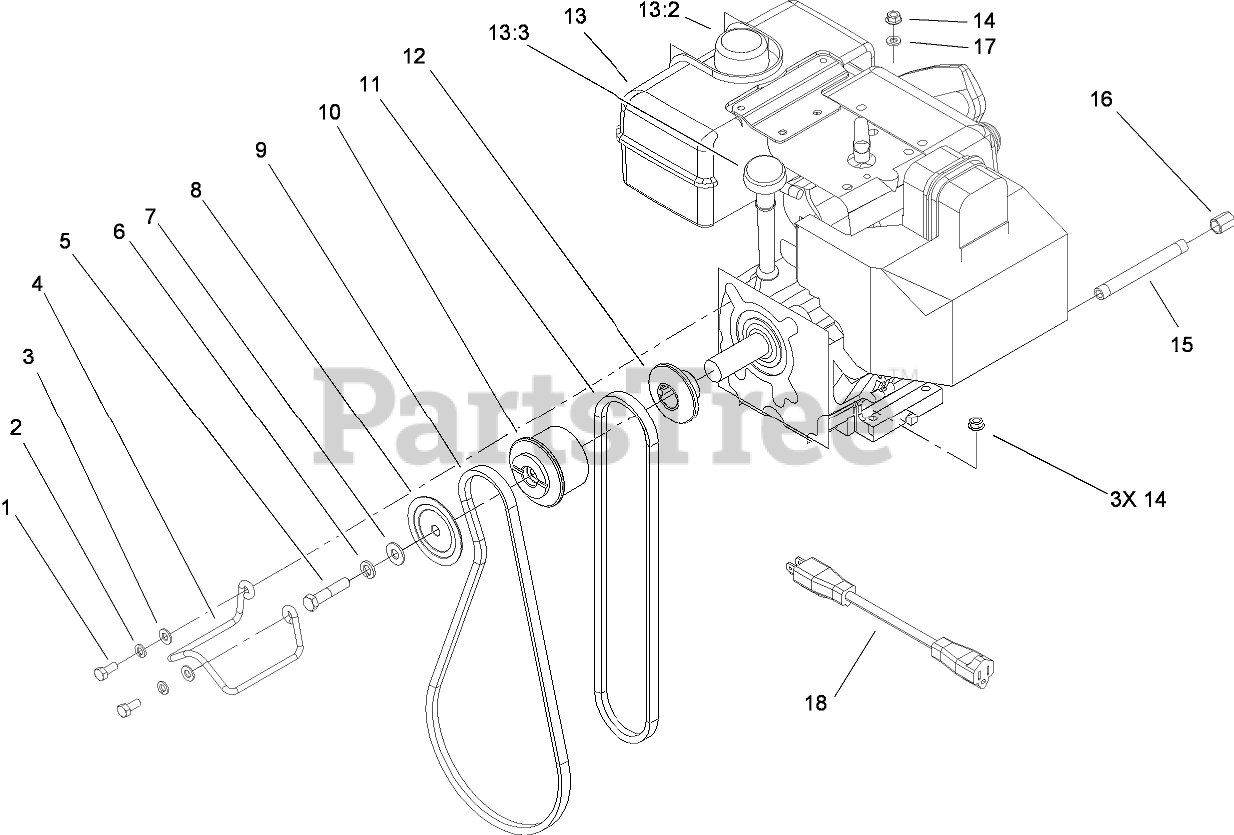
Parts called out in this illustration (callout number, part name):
1	SCREW-HH
2	WASHER-LOCK
3	WASHER-PLAIN
4	GUIDE-BELT
5	SCREW-HH
6	WASHER-LOCK
7	WASHER-FLAT
8	SHEAVE-HALF, IMPELLER
9	BELT-V
10	PULLEY-ENGINE, CENTER
11	V BELT-TRACTION
12	SHEAVE-HALF, TRACTION
13:2	CAP-FUEL
13:3	DIPSTICK
14	NUT-HF
15	NIPPLE-PIPE
16	CAP-PIPE
17	WASHER-FLAT
18	CORD-EXTENSION
